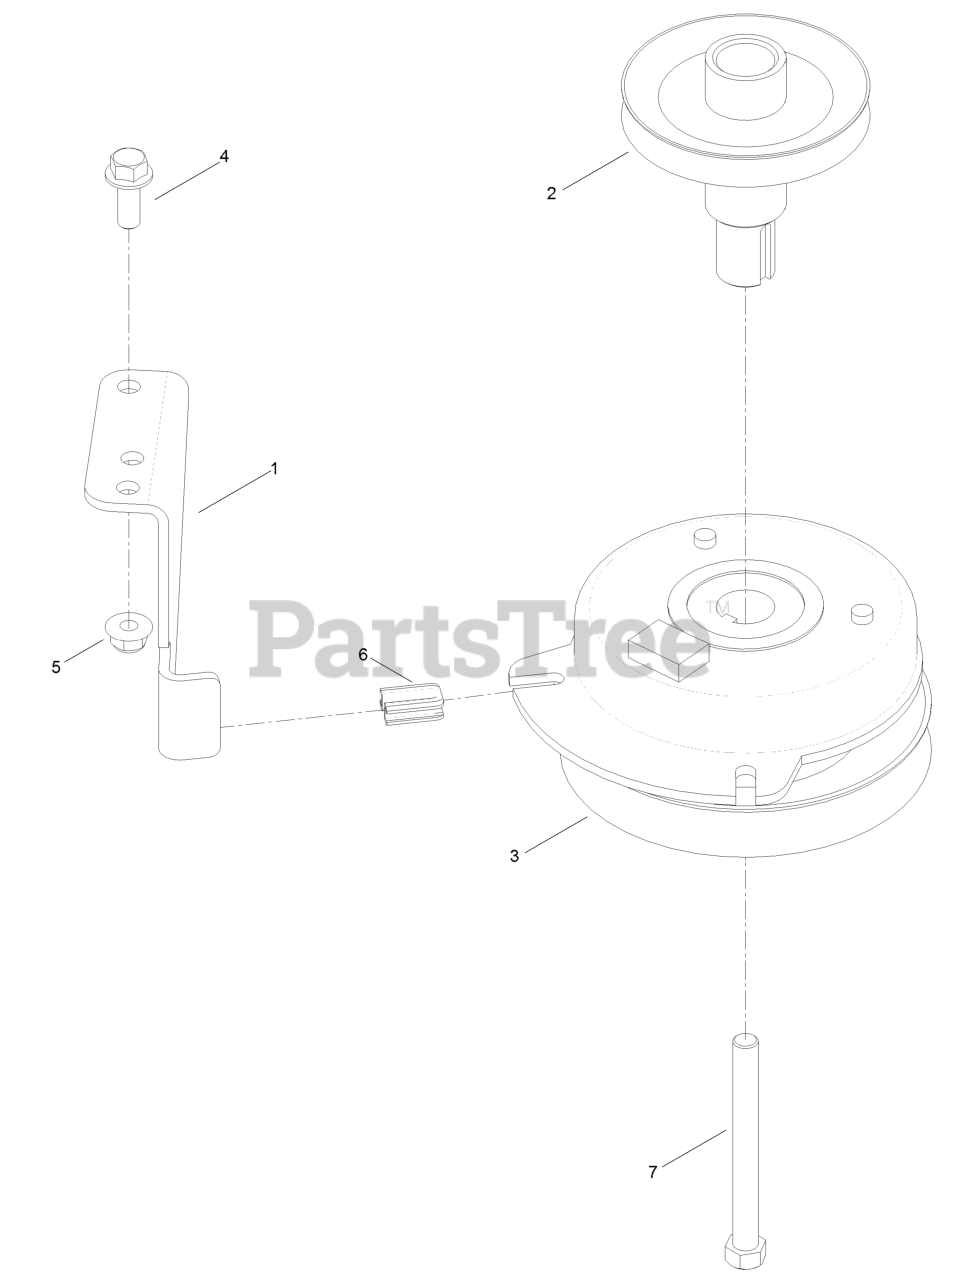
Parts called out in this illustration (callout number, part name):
1	STOP-CLUTCH
2	PULLEY-ENGINE
3	CLUTCH-PTO
4	SCREW-HHF 3/8-16 X 1
5	NUT-HF, NI
6	ISOLATOR-CLUTCH
7	SCREW-HH
